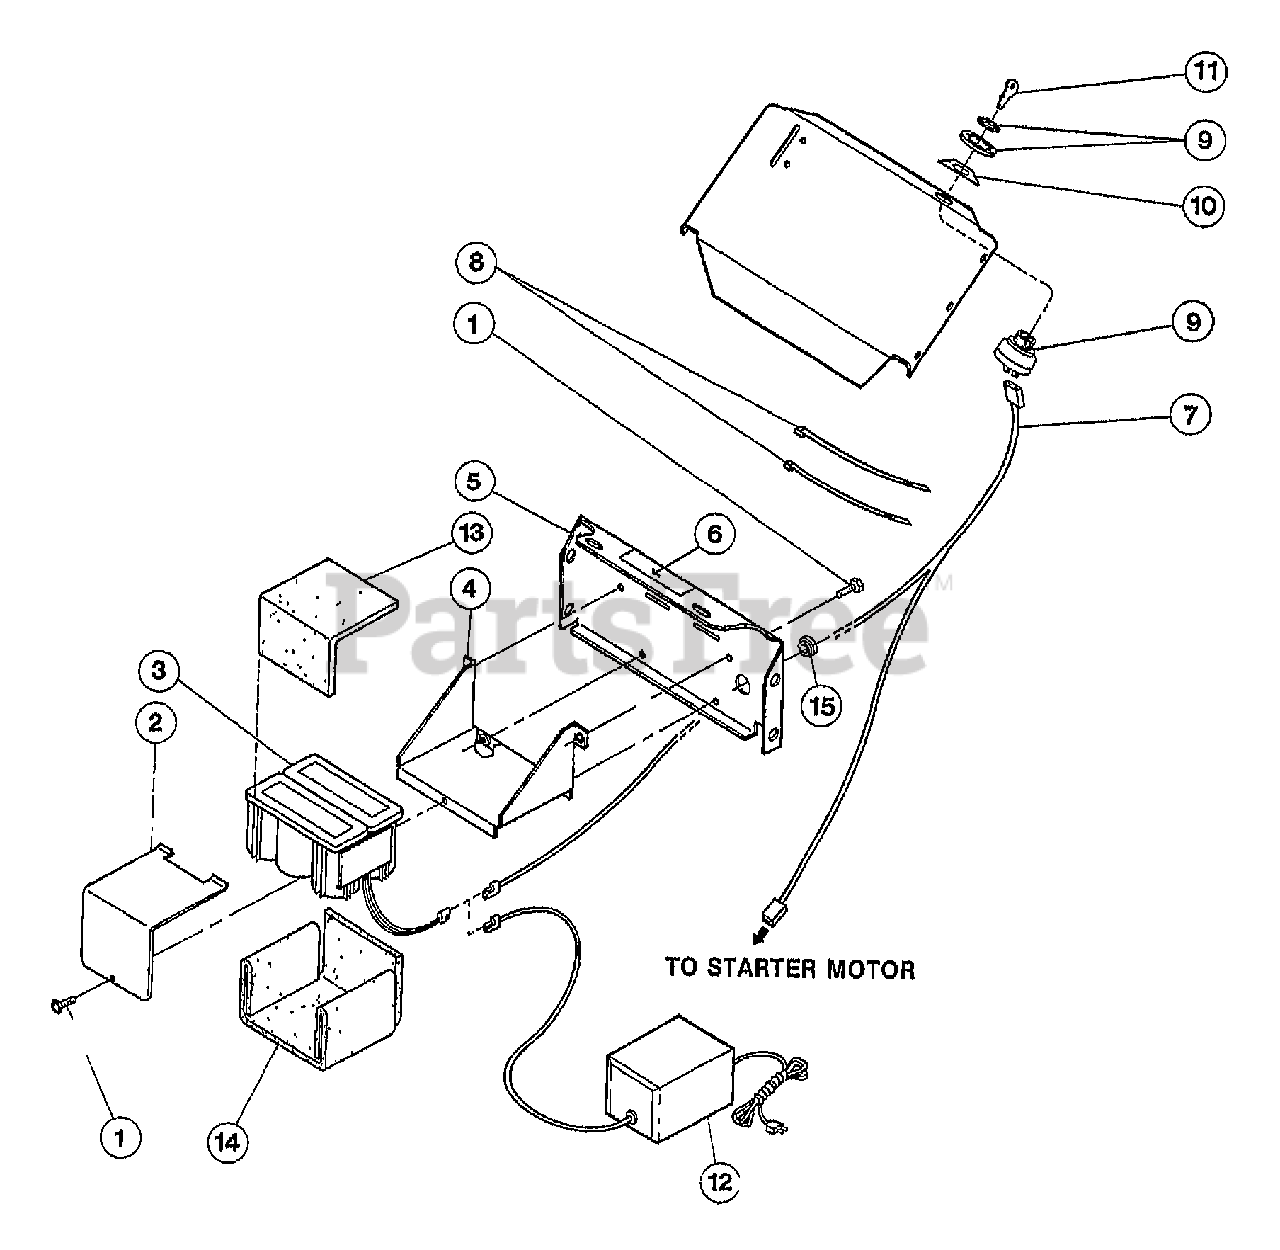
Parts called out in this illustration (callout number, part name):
1	SCR-H FL LK#10-32X.62 G5
2	CLAMP-40138P
3	BATTERY & WIRE-T/BLAZER
4	BRKT-BATTERY W/NUTSERT
5	HOOD, REAR, INCLUDES DECAL #40159 (INDEX #6)
6	DECAL-SHRT CIR/CHRG INSTR
7	HARNESS-WIRE SICKLEBAR
8	TIE-CABLE NYLON BLACK
9	SWITCH-EL IGNITION
10	DECAL-ENGINE IGNITION
11	KEYS-IGN T/BLAZER 1 PAIR
12	CHARGER-BATTERY TRAILBLAZER
13	TOP PAD-BATTERY CLAMP
14	BOTTOM PAD-BATTERY BRKT
15	BUSHING-SNAP .750X1.00
